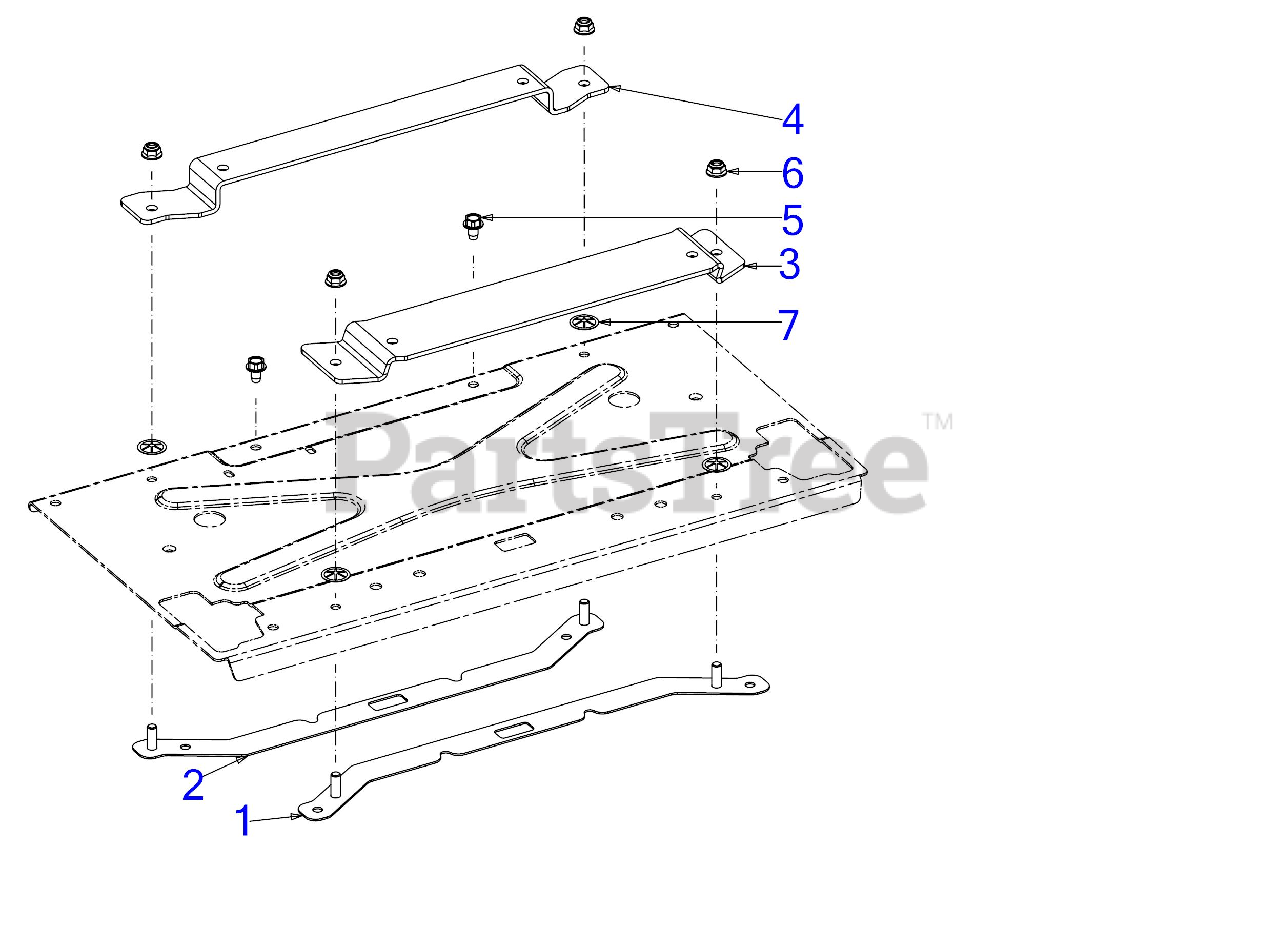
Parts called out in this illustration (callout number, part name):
5	SCREW 5/16-18 x .500
6	FLANGE LOCK NUT 5/16-18
7	PUSH ON NUT
